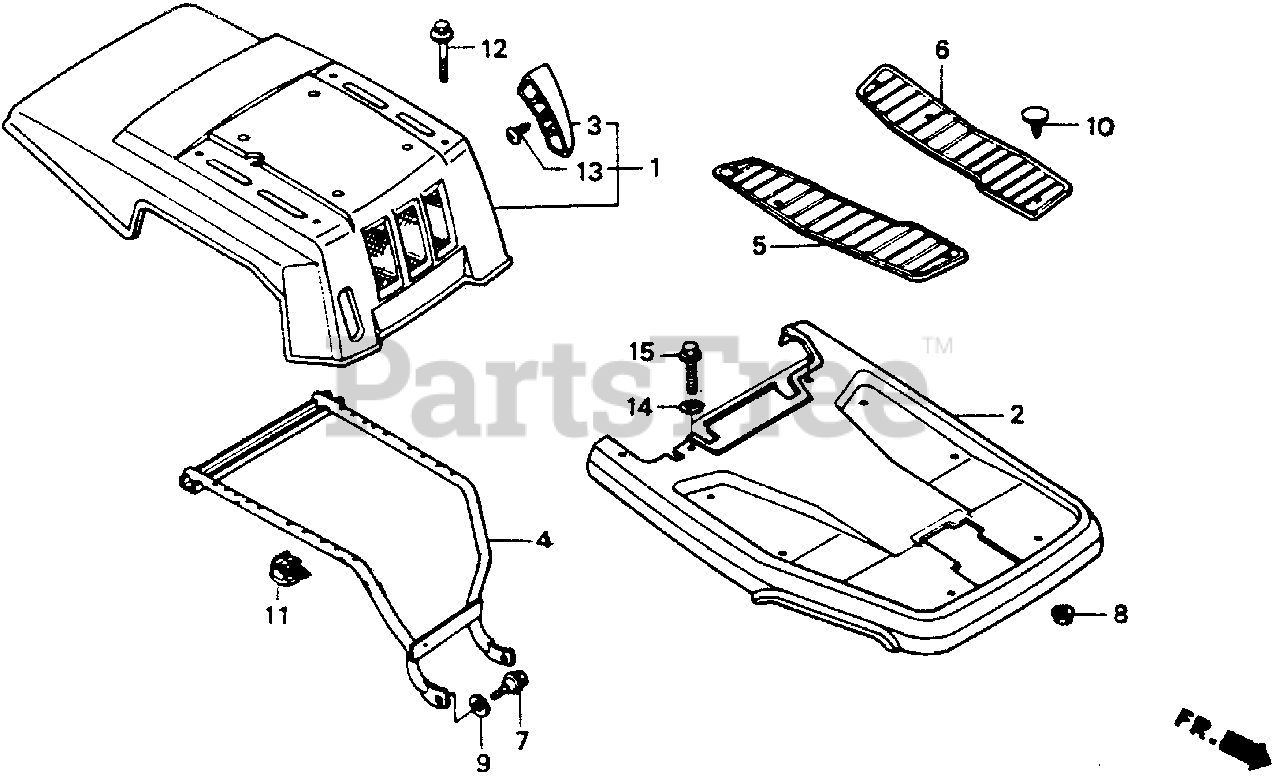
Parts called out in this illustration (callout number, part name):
1	BODY ASSY., RR.
2	FLOOR (NOT AVAILABLE)
3	INDICATOR, HEIGHT ADJUSTING
4	FRAME, SEAT
5	FLOOR MAT, R.
6	FLOOR MAT, L.
7	BOLT, HINGE (10MM)
8	NUT, FLANGE (6MM)
9	WASHER, LOCK (B)
10	CLIP, TRIM
11	CLIP, HARNESS (7MM)
12	BOLT-WASHER (6X35)
13	SCREW, TAPPING (6X12)
15	BOLT, FLANGE (6X12)
